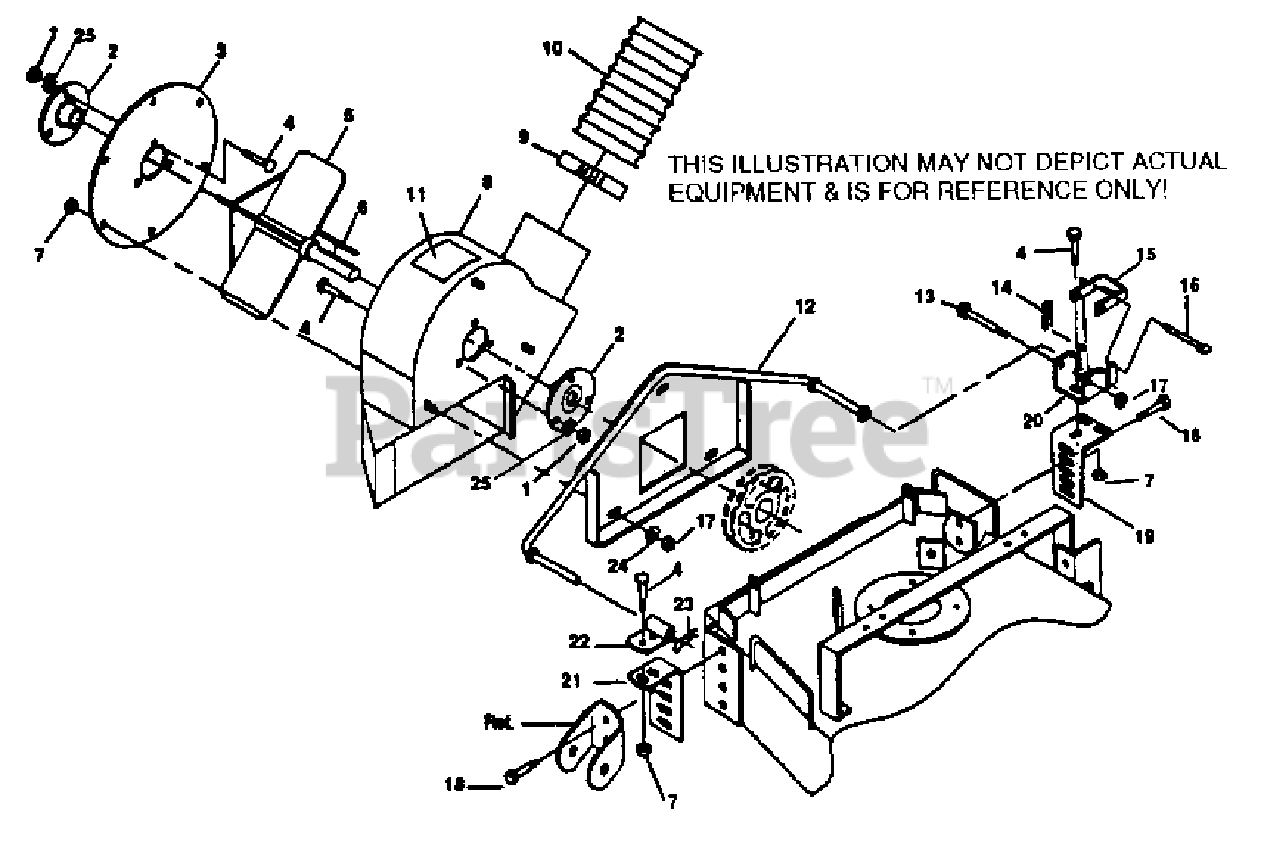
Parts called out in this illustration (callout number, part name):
1	NUT, ELASTIC STOP 5/16-18
2	BEARING ASSEMBLY
3	COVER BLOWER HOUSING
5	FAN WELDMENT
7	NUT, SERRATED FLANGE 5/16-18
8	BLOWER HOUSING WLDMT. W/DECAL
9	CLAMP, HOSE
10	HOSE, 6" X 48"
11	DECAL, DANGER
12	BLOWER MOUNTING WELDMENT
14	HAIR PIN, 3/32 DIA. X 1.62"
15	LATCH
16	RING PIN
17	NUT, ELASTIC STOP 3/8-16
18	CAPSCREW, SERR. FLANGE 3/8-16 X 1"
19	MOUNTING BRACKET, REAR
20	LATCH PLATE
21	MOUNTING BRACKET, FRONT
22	MOUNTING WELDMENT, FRONT
23	HAIR PIN, .148 DIA. X 2-3/4"
24	FLAT WASHER, 3/8(.391 X .938 X .105)
